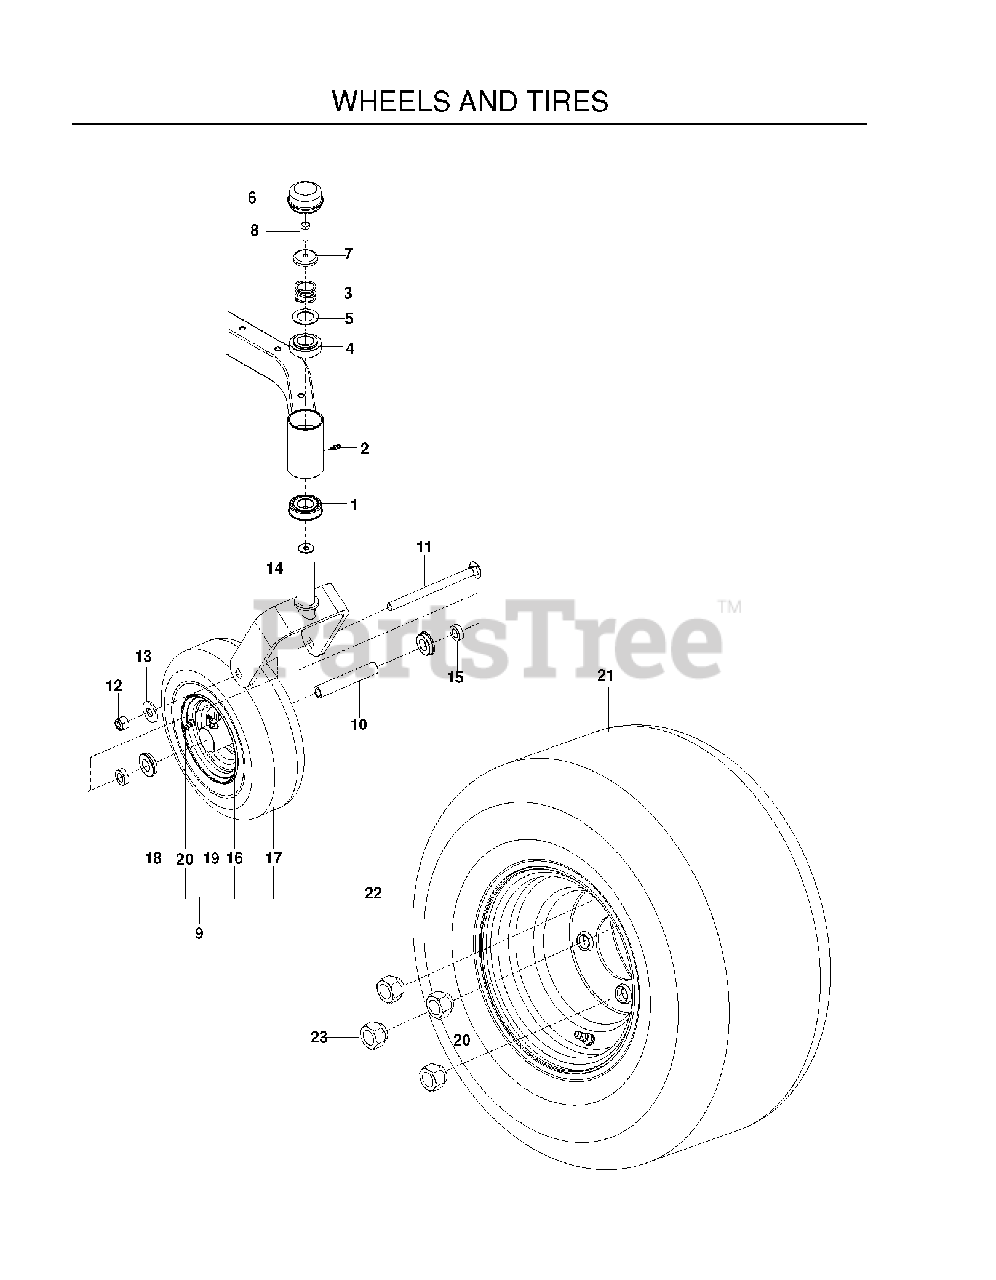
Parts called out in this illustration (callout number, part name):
1	BEARING FLANGED
2	ZERK, 3/16, DRIVE IN
3	SPRING, CASTER
4	BUSHING, CASTER
5	WASHER, 1.025 ID X 1.64
6	GREASE CAP
7	CASTER.PLUG
8	5/16-18X1 HHB G5W/NY
9	TIRE.CASTER.ASSEM.11X4-5.GR
11	RHSNB 1/2-13 X 6.50 GR2 ZD
12	RP NUT 1/2-13 HEX NYLOC ZD
13	WASH USS FLAT 1/2
14	YOKE.CASTER.ORANGE
15	SPACER, 5/16"
17	TIRE.11"X4"-5.4PLY.SMOOTH.KEND
18	BEARING RETAINER
19	ZERK
20	VALVE STEM TR-412
21	TIRE ASM 18 X 8.5-8
22	RIM.8X7.SILVER.ZTR
23	LUG NUT 1/2F
